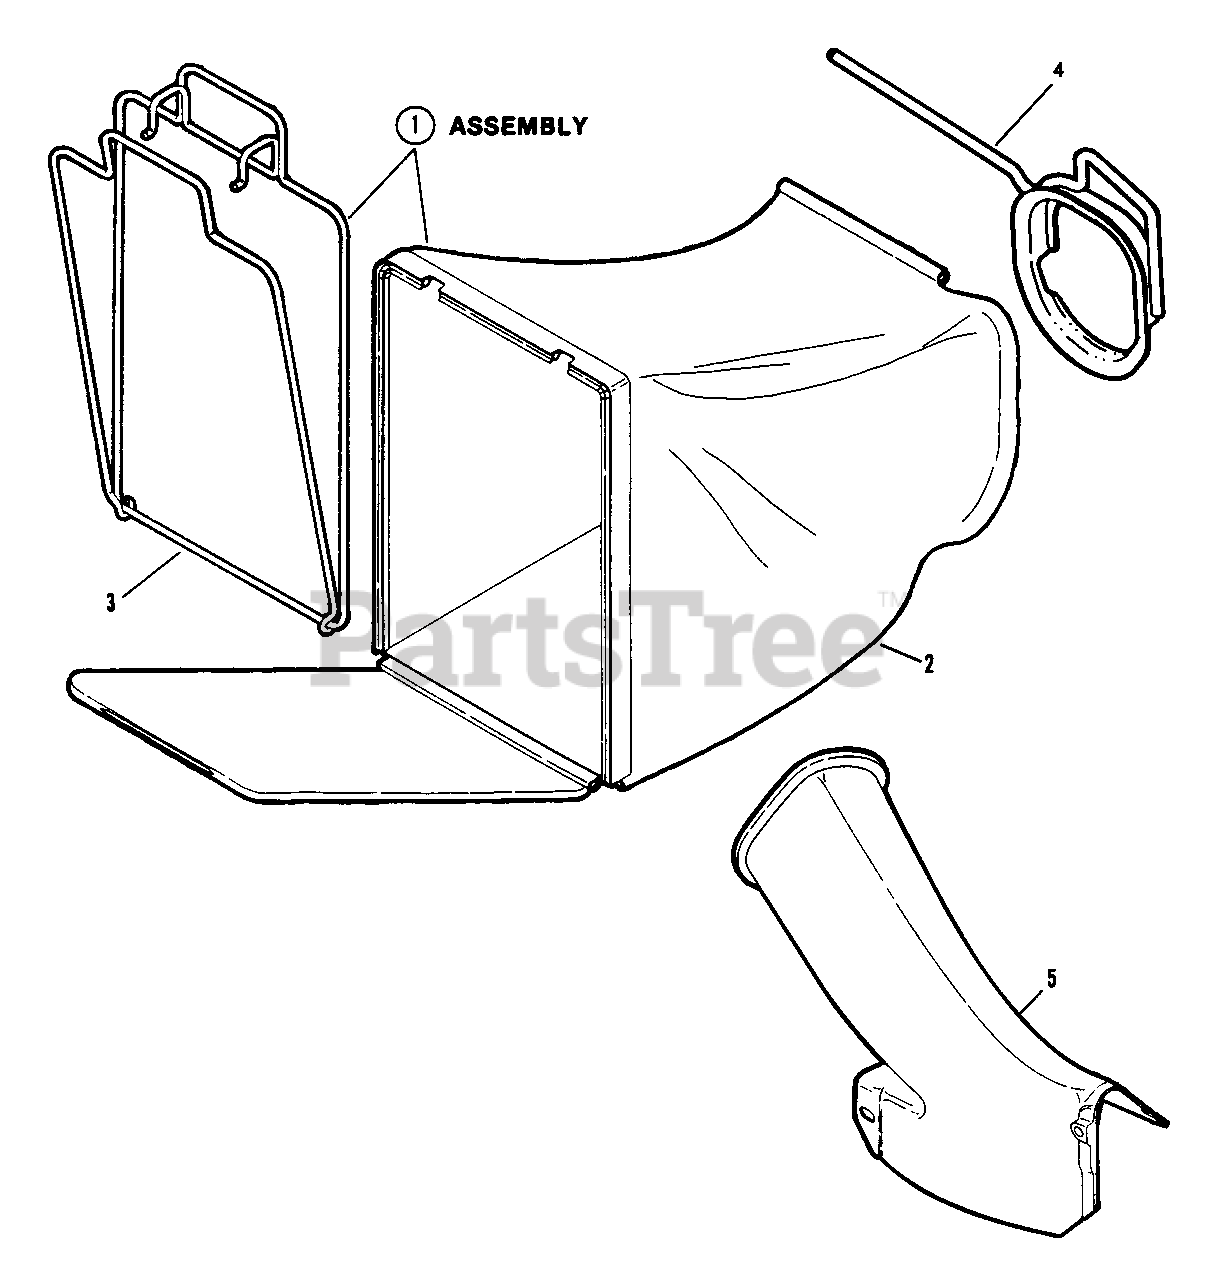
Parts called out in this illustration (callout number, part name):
1	ASSEMBLY, Grass Bag (12.5" Wide)(Incl. 75765, 51906, 42489)
1	ASSEMBLY, Grass Bag (11" Wide)(Incl. 16005, 51889, 42489)
2	BAG, Door Type (Wide = 14.5") (Black)
2	BAG, Door Type (Wide = 13") (Black)
2	BAG, Door Type (Narrow = 11") (Black)
3	ASSEMBLY, Bag Wire (14" Wide)
3	ASSEMBLY, Bag Wire (12.5" Wide)
3	ASSEMBLY, Bag Wire (11" Wide)
4	CONNECTOR, Grass Bag
5	ADAPTER, Bag
